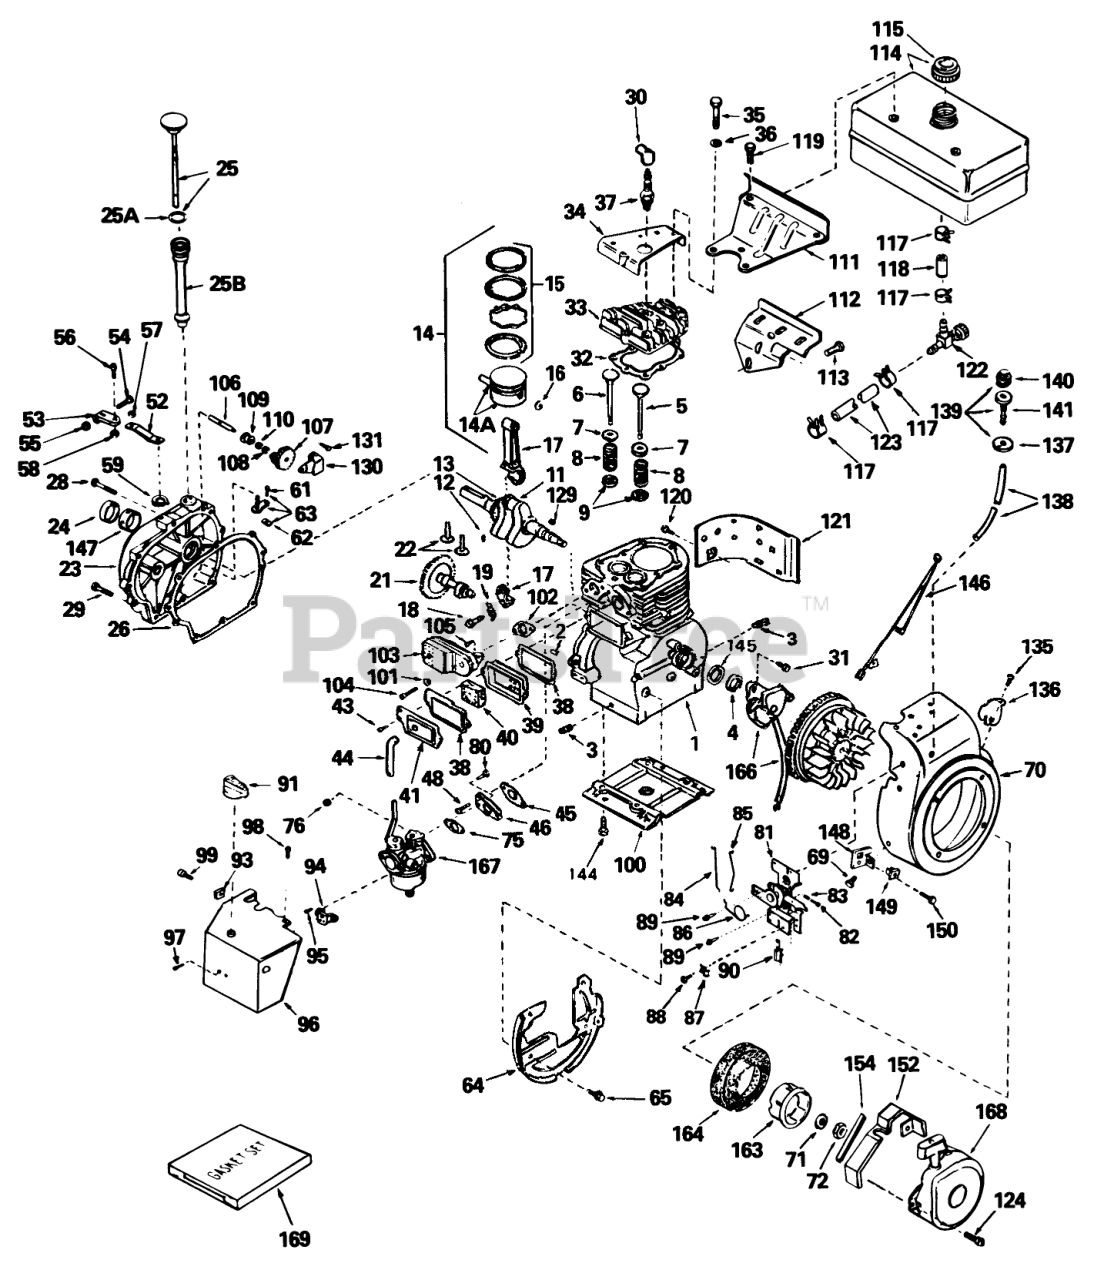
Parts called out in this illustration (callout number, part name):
1	Cylinder Assy. (Incl. Ref. #2, 3 & 4)
2	Pin-Dowel
3	Plug-Drain, Oil (SQH 1/4-18)
4	Oil Seal
5	Valve, Intake (Std.)(Incl. Ref. #9)
5	Valve, Intake (1/32" Oversize)(Incl. Ref. #9)
6	Valve, Exhaust (Std.)(Incl. Ref #9)
6	Valve, Exhaust (1/32" Oversize)(Incl. Ref. #9)
7	Cap-Spring, Valve
8	Spring-Valve
9	Keeper-Spring, Valve
11	Crankshaft Assy. (Incl. Ref #12 & 13)
12	Pin, Groove
13	Gear-Crankshaft
14	Piston, Pin & Ring Assy. (Incl. Ref. #14A, 15& 16)(Std.)
14	Piston, Pin & Ring Assy. (Incl. Ref. #14A, 15 & 16)(.010 Oversize)
14	Piston, Pin & Ring Assy. (Incl. Ref. #14A, 15 & 16)(.020 Oversize)
14A	Piston & Pin Assy. (Incl. Ref. #16)(Std.)
14A	Piston & Pin Assy. (Incl. Ref. #16)(.010 Oversize)
14A	Piston & Pin Assy. (Incl. Ref. #16)(.020 Oversize)
15	"O"Ring
15	Ring Set (.010" OS)
15	Ring Set (.020" OS)
16	Ring-Retaining, Piston Pin
17	Rod Assy., Connecting (Incl. Ref #18 & 19)
18	Bolt, Connecting Rod
19	Dipper-Oil
21	55012A GIL SNWTHWR
22	Lifter-Valve
23	Cover, Cylinder (Incl. Ref. #24, 106, & 147)
24	Oil Seal
25	Dipstick, Oil (Incl. Ref. #25A)
25B	Tube Fill
26	Gasket-Cover, Cylinder
28	Screw (1/4-20 x 1-1/4)
30	Cover-Spark Plug
32	Gasket-Cylinder Head
33	Head, Cylinder (Incl. 3 of Ref. #35)
34	Cover-Head, Cylinder
35	Screw (5/16-18 X 2-1/2)
36	Washer-Flat
37	Plug, Spark (J17LM or equiv.)
37	Plug, Spark (Champion RCJ-8)
38	Gasket-Breather
39	Body-Breather
40	Element-Breather
41	Cover-Valve
44	Tube-Breather
45	Gasket-Intake
46	Flange, Carburetor (Incl. Ref. #76 & 80)
52	Lever-Governor
53	Clamp-Lever, Governor
55	Nut-Lock
56	Screw
57	Washer-Lock
58	Nut-Lock
59	Ring-Retaining
61	Screw (6-40x5/16)
62	Yoke-Governor
63	Rod Assy., Governor (Incl. Ref. #61 & 62)
64	Baffle Blower Housing
65	Screw (1/4-20x19/32)
69	Screw, Hex Hd.
70	Housing, Blower (Incl. Ref. #135 & 136)
71	Washer
75	Gasket-Carburetor
76	Nut and Lock Washer (1/4-28)
80	Screw
81	Control Assy., Speed (Incl. Ref #82, 83, 86 & 90)
82	Screw
83	Spring-Compression
84	Governor Link
85	Link-Throttle
86	Spring-Throttle
87	Conduit
88	Screw (10-32 x 3/8)
89	Screw (10-32 x 1/2)
90	Terminal
91	Knob-Control
93	Nut-U Type
94	Bracket-Choke
95	Screw (10-32 x 1/2)
96	Cover, Carburetor
97	Screw (8-32 X 5/16)
98	Screw (10-32x1/2)
99	Screw (8-32 x 3/8)
100	Base Engine
102	Gasket Exhaust
103	Muffler
104	Screw (5/16-18 X 2)
106	Shaft-Governor
107	Gear Assy., Governor (Incl. Ref. #110)
108	Ring-Retaining
109	Spool-Governor
110	Washer-Flat
111	Bracket-Fuel Tank
112	Bracket-Fuel Tank
113	Screw (1/4-20x19/32)
114	Tank Assy., Fuel (Incl. Ref. #115)
115	Cap, Fuel
117	Clamp-Line, Fuel
118	Line-Fuel
119	Screw (1/4-15x7/8)
121	Emnsion, Blower Housing
122	Valve-Shut Off
123	Line-Fuel (8.62)
129	Key-Flywheel
130	Bracket, Governor
131	Screw (10-32 x 35/64)
135	Screw (8-32 x 3/8)
137	Retainer, Primer Bulb
138	Line, Primer
139	Primer Assy. (Incl. Ref. #137, 140 & 141)
140	33164A GILO"HITCH A
141	Body Primer
145	Gasket Stator
146	Wire, Ground
147	Bushing-Crankshaft
148	Bracket
149	Grommet
150	Screw
152	Guard-Starter
154	Seal, Snowguard
163	Cup-Starter
164	Screen, Air
167	Carburetor (Incl. Ref. #75)
168	Starter Assy., Rewind
169	Gasket Set
